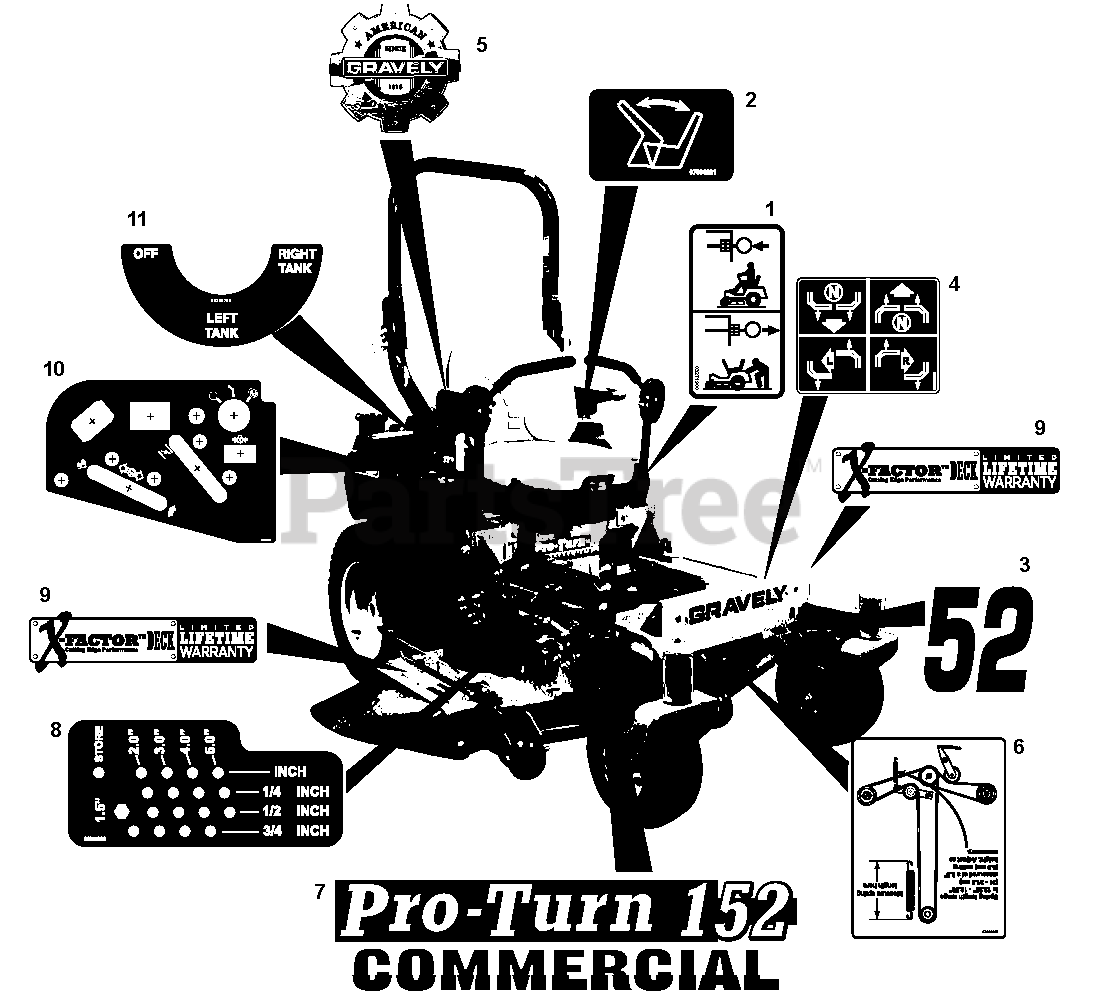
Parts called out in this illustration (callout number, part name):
1	Decal, Transmission Disconnect
2	Decal, Seat Release
3	Decal, 48 (991079, 095, 102)
4	Decal, Instructional-Steering
5	Decal, Gravely Heritage, Large
6	Decal, Belt Routing (991079, 080, 095, 096, 102, 103)
7	Decal, Pro-Turn 148 (991079, 095, 102)
8	Decal, Height of Cut
9	Decal, X-Factor Deck
10	Decal, Control Panel (991079, 080, 081, 102, 103, 104)
11	Decal, Fuel Valve
